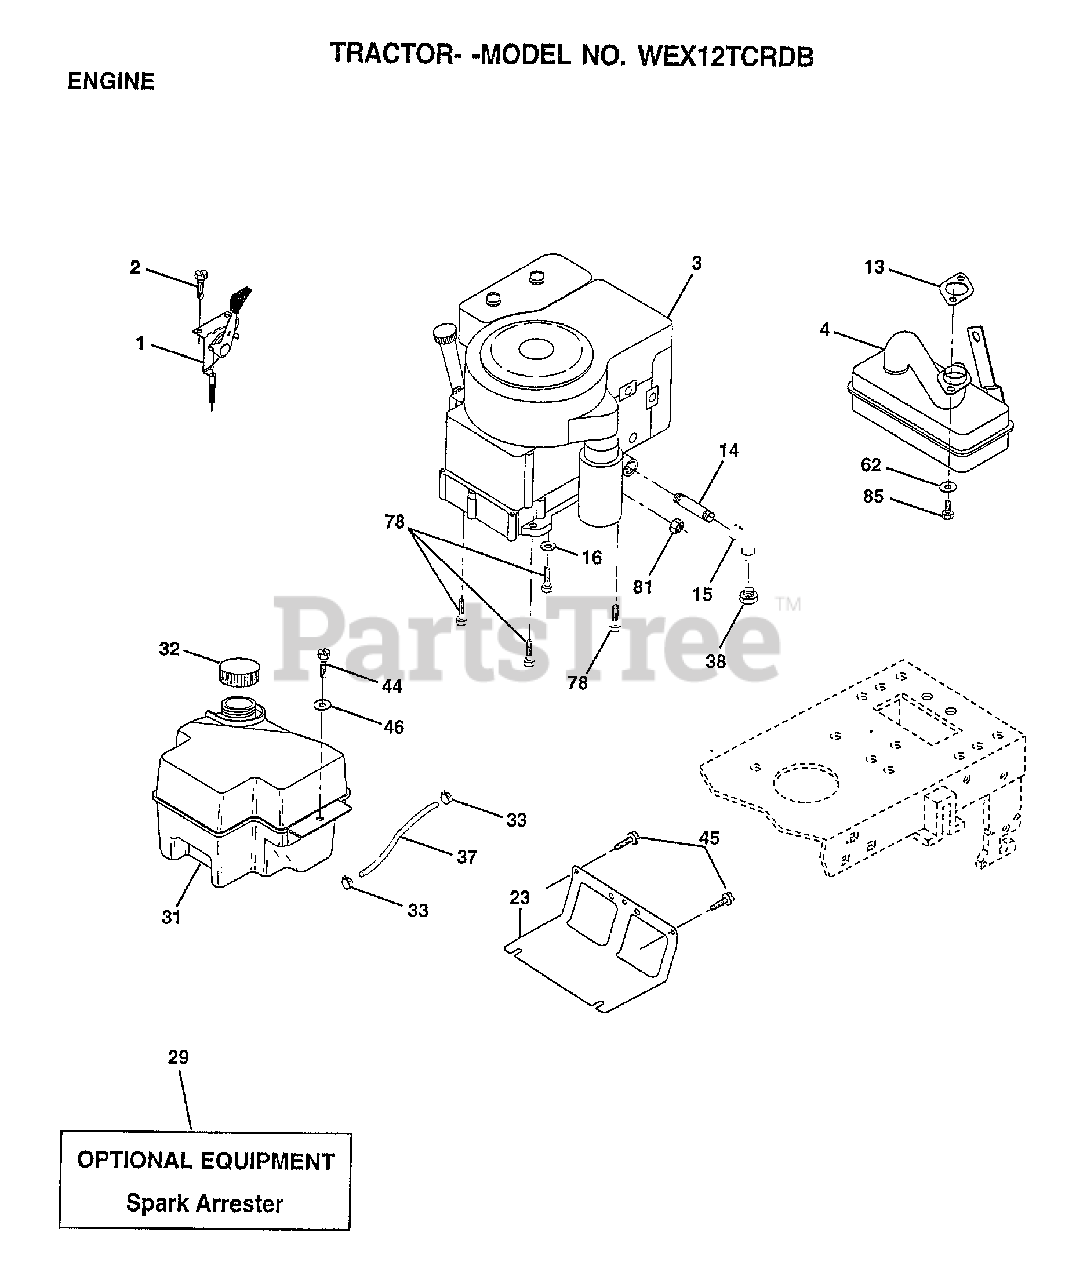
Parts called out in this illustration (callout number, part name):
1	CONTROL-THROT/CHO
2	SCREW LT
4	MUFFLER TEC. 13HP
14	PIPE NIPPLE LT
15	ELBOW
16	LOCKWASHER
23	SHIELD BROWNING
31	TANK.FUEL.LT.
32	CAP ASM FUEL
33	HOSE CLAMP
37	LINE FUEL
44	SCREW
45	SCREW
46	WASHER
62	LOCKWASHER
78	SCREW
81	NUT
85	SCREW HEX HD CAP
